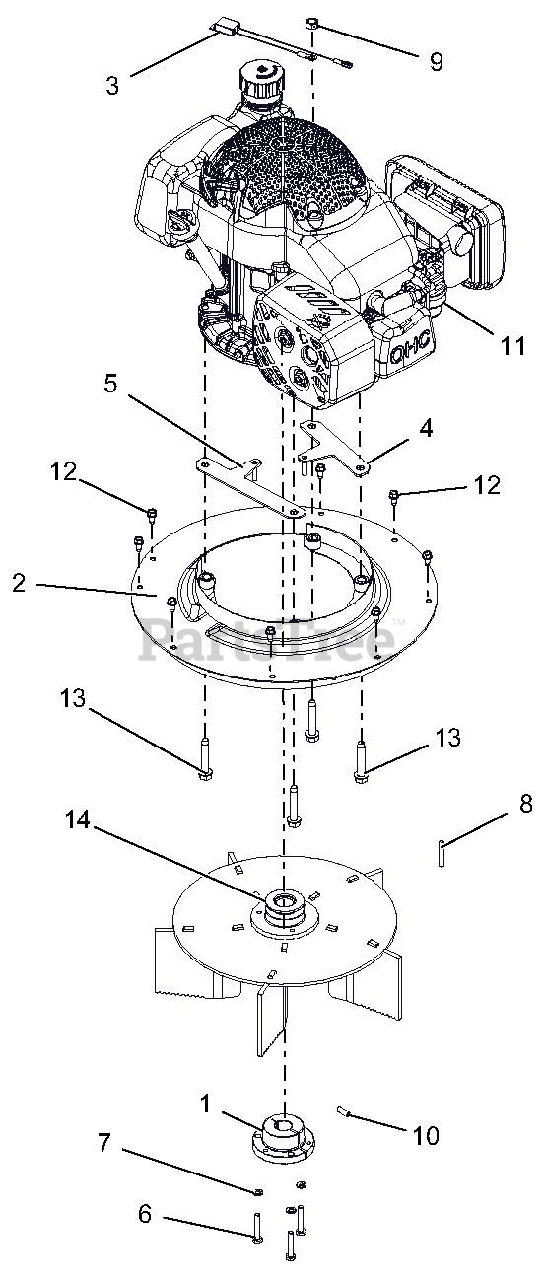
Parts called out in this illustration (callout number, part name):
1	BUSHING, TAPER-SPLIT 7/8"(SDS)
2	WMT-ENGINE PLATE
3	WIRE HARNESS-APV
4	WLDMT, BRKT - APV BELT FNGR L
5	WLDMT, BRKT - APV BELT FNGR R
6	BLT-HEX .25-20X1.5 FTHD GR5 ZC
7	@WSHR-LK .25X.062 REG YWZC
8	KEY-SQ .188X1.50X.188
9	@NUT-LK-CTR .38-16 YWZC
10	SCR,SET .25-20X.75 PCPT SH
11	ENGINE-SUBARU EA190V CE
12	SCR-TAP .25-20X.50 HWH TR YWZ
13	SCR-TAP .38-16X2.00 HWH TR YZ
14	WLDMT, IMPELLER - APV TAPER
